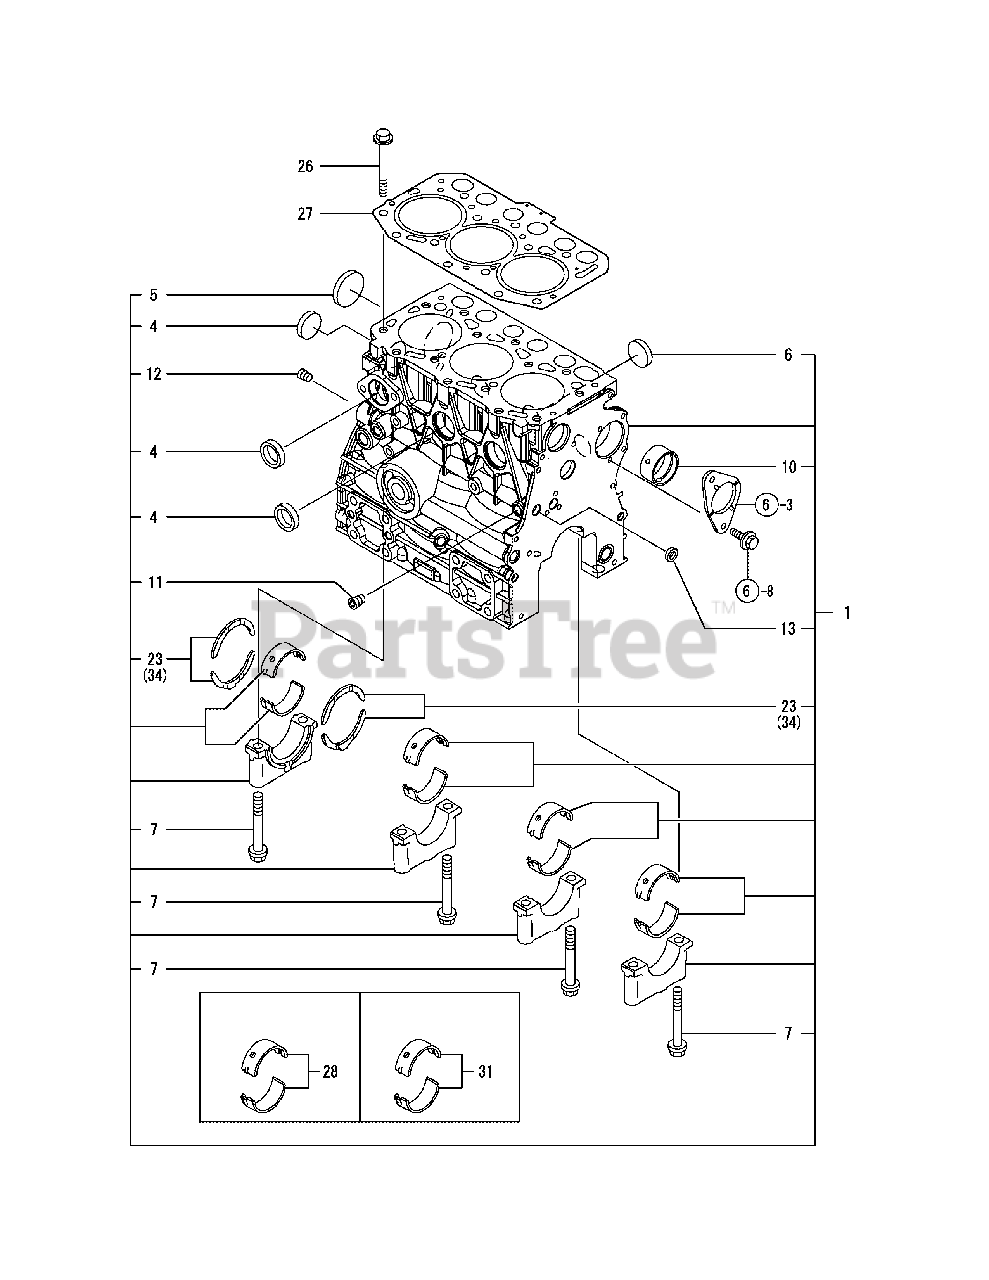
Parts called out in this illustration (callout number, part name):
1	Block Assembly, Cylinder
10	Bush, Camshaft
23	Bearing, Thrust
26	Bolt, Cylinder Head
27	Gasket, Cylinder Head
28	Main Bearing Set
34	Bearing, Thrust
